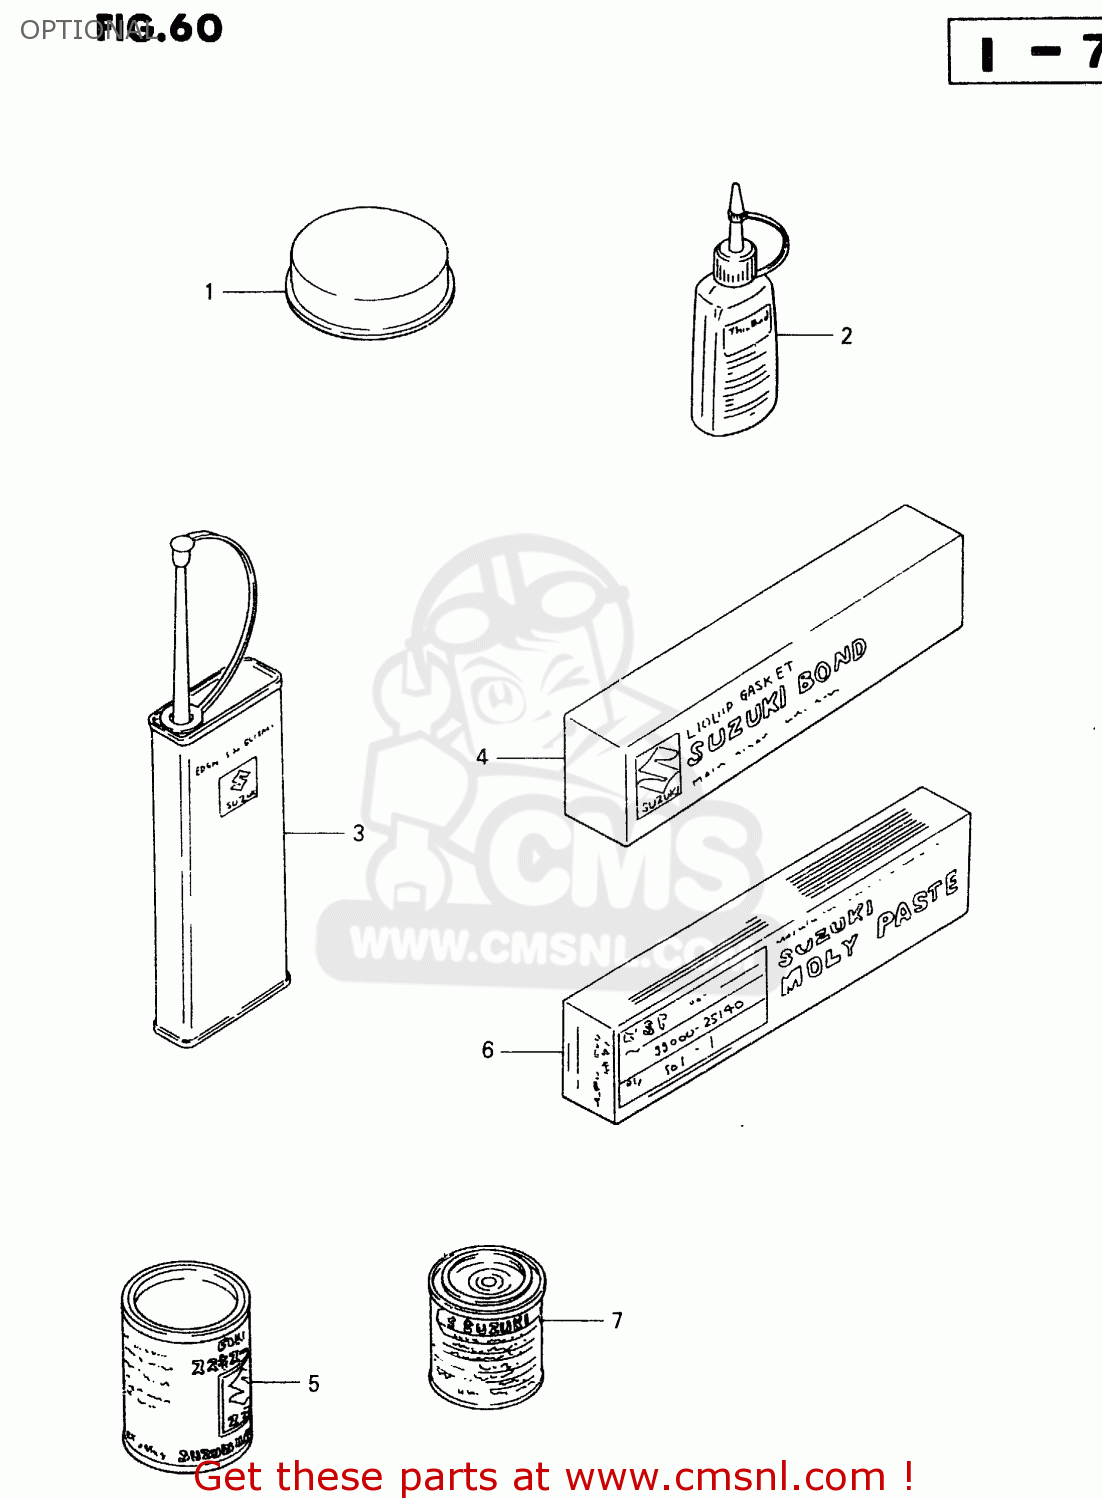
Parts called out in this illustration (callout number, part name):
1	GREASE,PBC FOR BRK PAD 20G
2	THREAD LOCK NO.1342
3	THREAD LOCK NO.1401 CLEAR 200G
4	LIQUID GSKT NO.1215 250G
5	GREASE(C)EP2 LITHIUM 150G
6	SUZUKI MOLY PASTE
7	PAINT,BLACK
